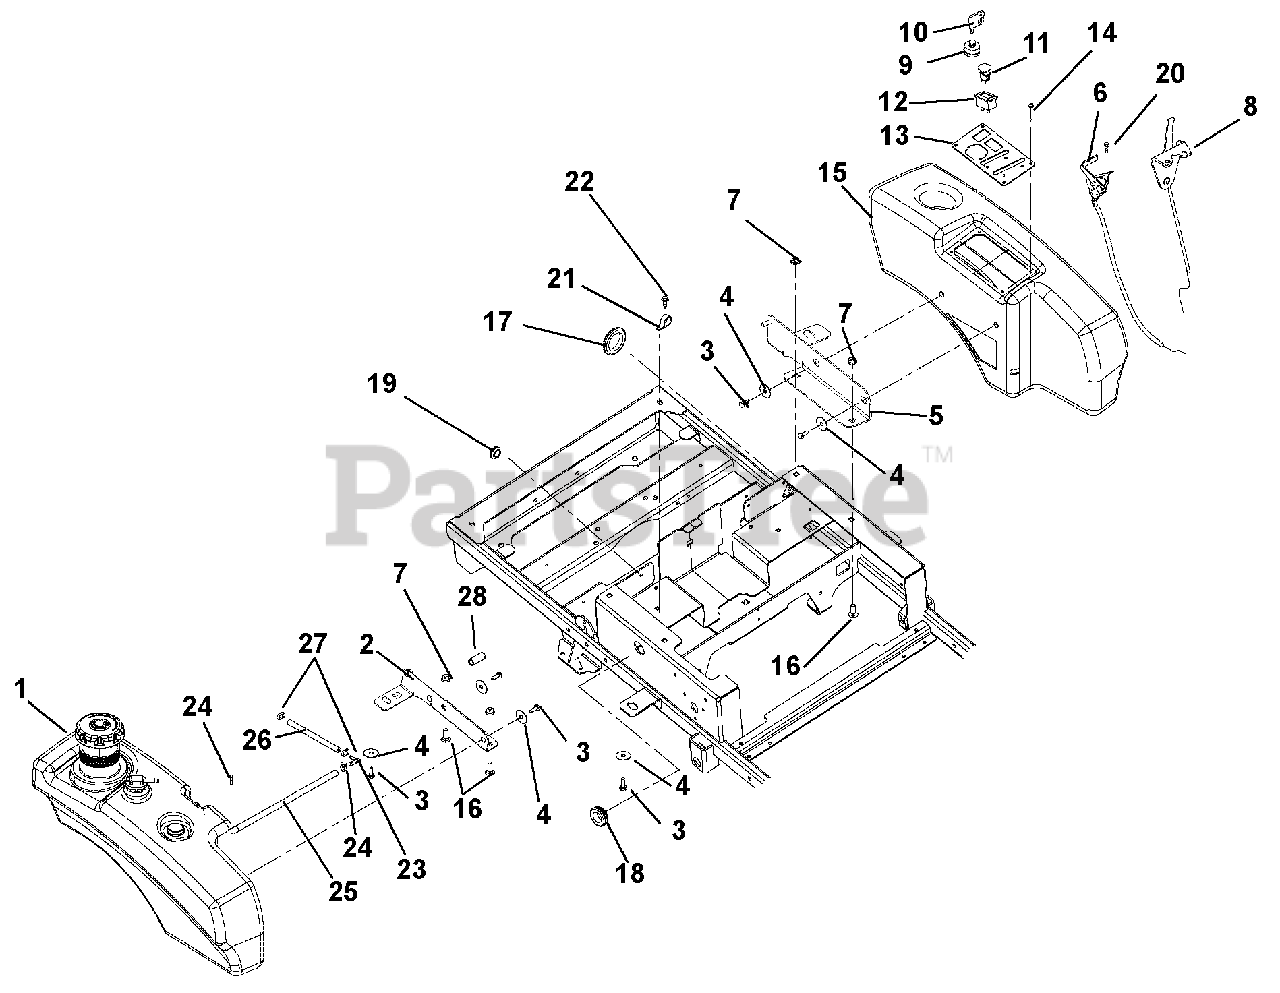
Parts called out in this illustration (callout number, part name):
1	Tank, XL Non-Permeable Fuel
2	Weldment, RH Tank Mount
3	Bolt, Serrated Hex Flange Washer Head .312-18 x .50
4	Washer, Flat Steel .347 x 1.254 x .048
5	Weldment, LH Fender Mount
6	Cable, Throttle
7	Nut, .38-16 Nyloc Flange
8	Cable, Choke
9	Key Switch
10	Key, w/Cap
11	Switch, Clutch
12	Hour Meter, Digital
13	Panel, Control
14	Screw, Hex .25 x 14-.75
15	Fender, XL
16	Bolt, Round Head Square Neck .38-16 x 1.00 Grade 5
17	Grommet, 2.00"
18	Grommet .125 x 1.000 ID
19	Grommet, Rubber 5/8 ID/1.13 OD
20	Screw, Tapping 10-24 x .50 Hex Washer Head Thread
21	Clamp, Cushioned Steel
22	Screw, Tap Hex Washer Head .38-16 x .5
23	Fitting, 3/16 x 1/4 90 Degree VAC
24	Clamp, Fuel Line
25	Hose, .25 Low-Perm Bulk Gas
26	Hose, .188 Low-Perm Bulk Gas
27	Clamp, Hose, Spring .188
28	Cap, End .315 x 1.00
